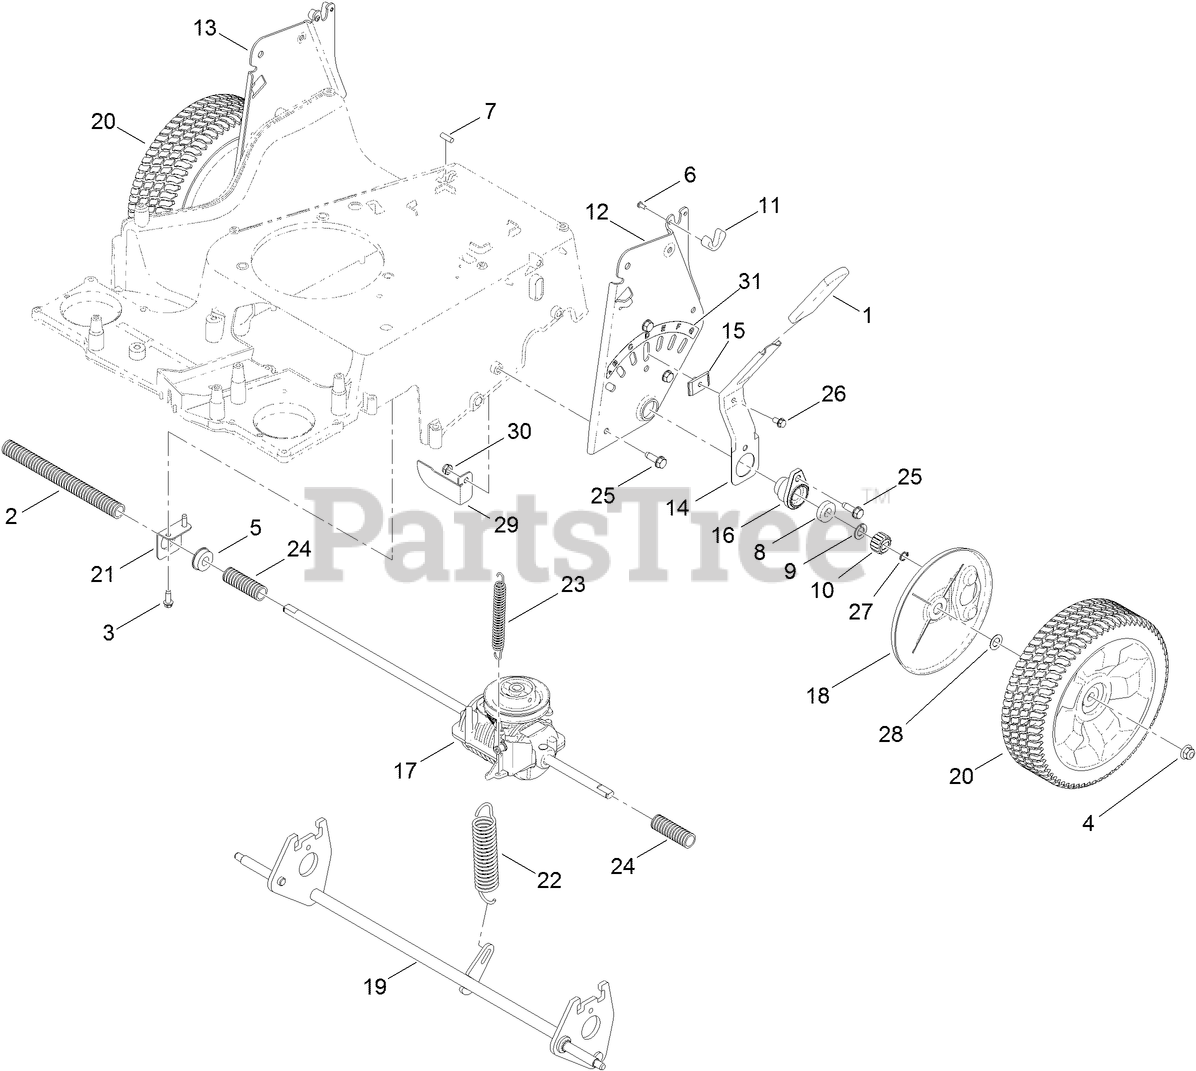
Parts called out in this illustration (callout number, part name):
1	GRIP-LEVER, LIFT
2	CONDUIT-CONVOLUTED
3	SCREW-HWHTF
4	NUT-HF, NI
5	BEARING-BALL
6	SCREW-PPH
7	PIN-STOP
8	BEARING-BALL
9	WASHER-THRUST
11	ANCHOR-BAG
12	PLATE-HOC, LH
13	PLATE-HOC, RH
14	ARM-SPRING, REAR
15	KEY-SPRINGARM
18	COVER-GEAR
20	10 INCH WHEEL GEAR ASM
22	SPRING-EXTENSION
23	SPRING-EXTENSION
24	CONDUIT-CONVOLUTED
25	SCREW-THD ROLL, HWH
26	SCREW-HWH
27	RING-RETAINING
28	WASHER-PLAIN
30	NUT-LOCK, NI
31	DECAL-HOC, REAR
